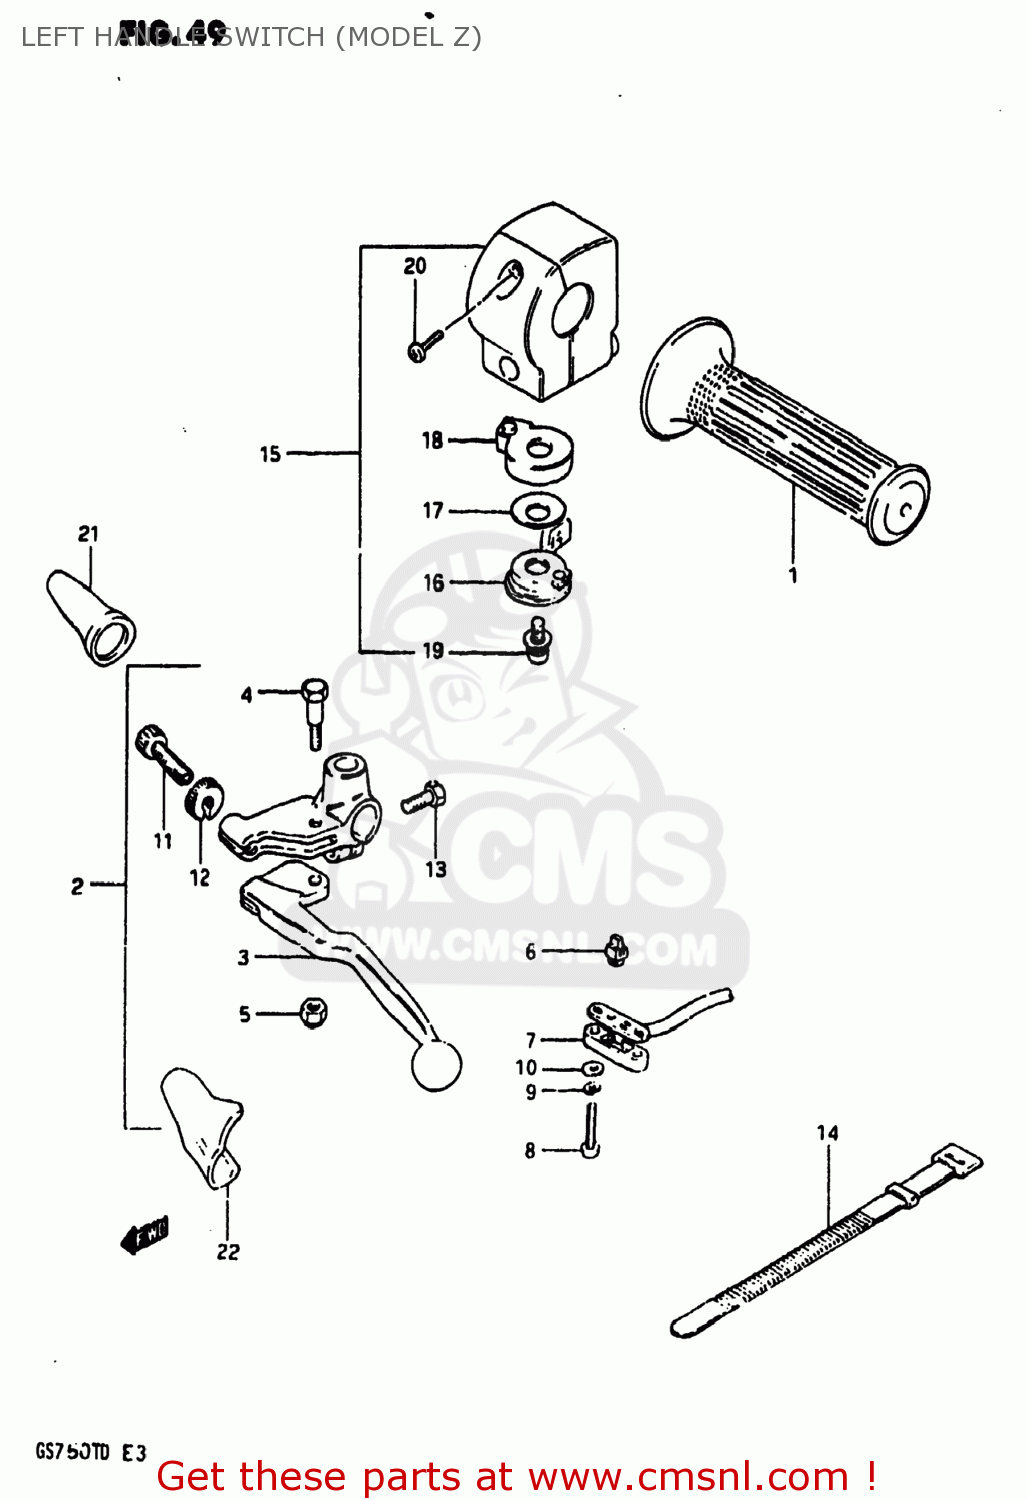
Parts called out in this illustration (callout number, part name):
1	GRIP,LEFT
2	LEVER ASSEMBLY
3	LEVER,CLUTCH
4	BOLT,LEVER
5	NUT 6MM
6	CONTACT,SWITCH
7	COVER,FR BK TERMINAL BASE
8	SCREW
9	LOCK WASHER
10	WASHER
11	ADJUSTER,CABLE
12	NUT,CABLE ADJUSTER
13	BOLT,CLUTCH LEVER HOLDER
14	CLAMP(L:120)
15	SWITCH ASSEMBLY,HANDLE,LEFT
16	LEVER,STARTER
17	WASHER,ADJUSTER
18	BODY,CHOCK
19	SCREW,CHOKE LE
20	SCREW
21	BOOT,CLUTCH CABLE
22	COVER,CLUTCH LEVER
23	BUTTON,STARTER
24	SPRING,STARTER BUTTON
25	CONTACT,STARTER BUTTON
